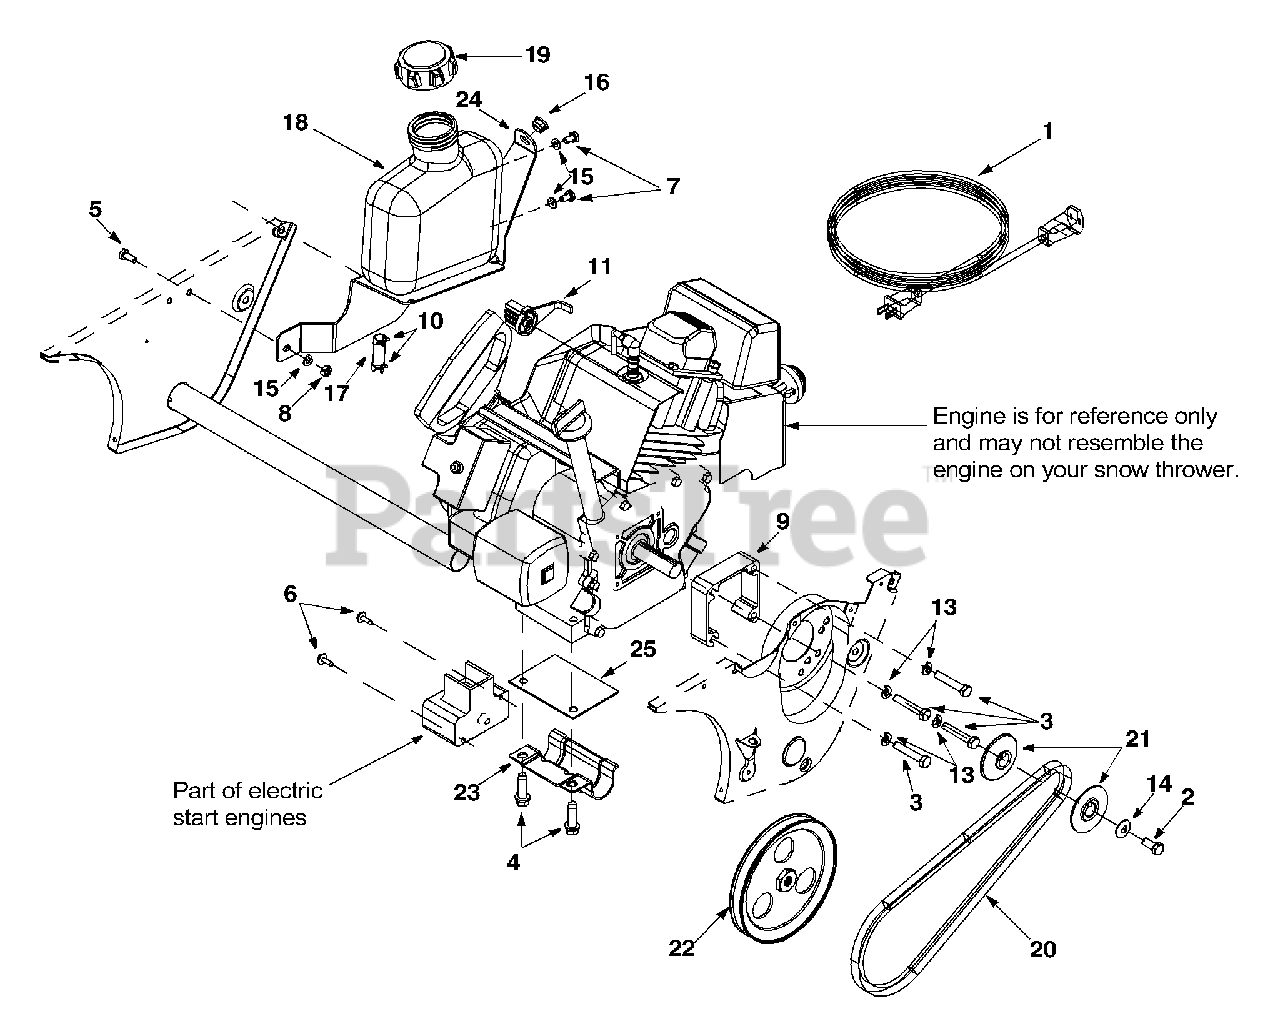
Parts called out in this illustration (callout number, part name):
1	Extension Cord
2	Hex Bolt 5/16-24 x 0.75"
3	Hex Bolt 5/16-24 x 1.75"
4	TT Sems Screw
5	Hex Screw 1/4-20 x 0.620"
6	B Screw #10-16 x 0.625"
7	Hex Screw 1/4-20 x 0.50"
8	Hex Nut 1/4-20
9	Spacer
10	Hose Clamp
11	Choke Knob
13	Lock Washer
14	Beleville Washer
15	Lock Washer
16	Plastic Bushing
17	Fuel Line Hose
18	Gas Tank
19	Fuel Cap
20	V-Belt
21	V-Pulley Half
22	Pulley
